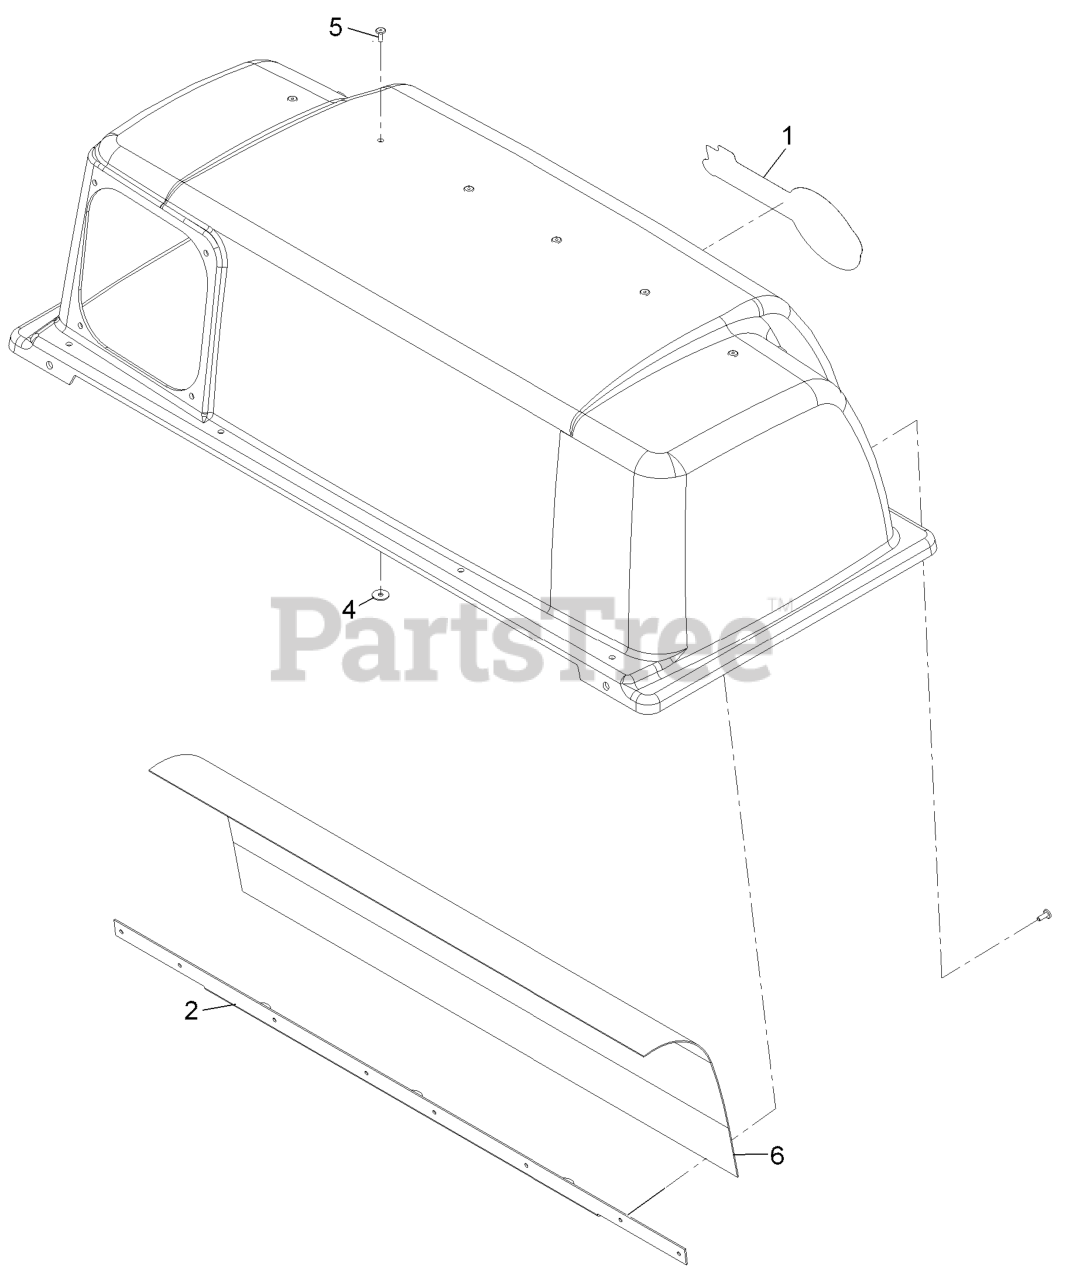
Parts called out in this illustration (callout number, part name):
1	DECAL, EXMARK LOGO
2	SUPPORT-SCREEN
4	WASHER-FLAT
5	RIVET-BLIND
6	SCREEN-BAGGER
